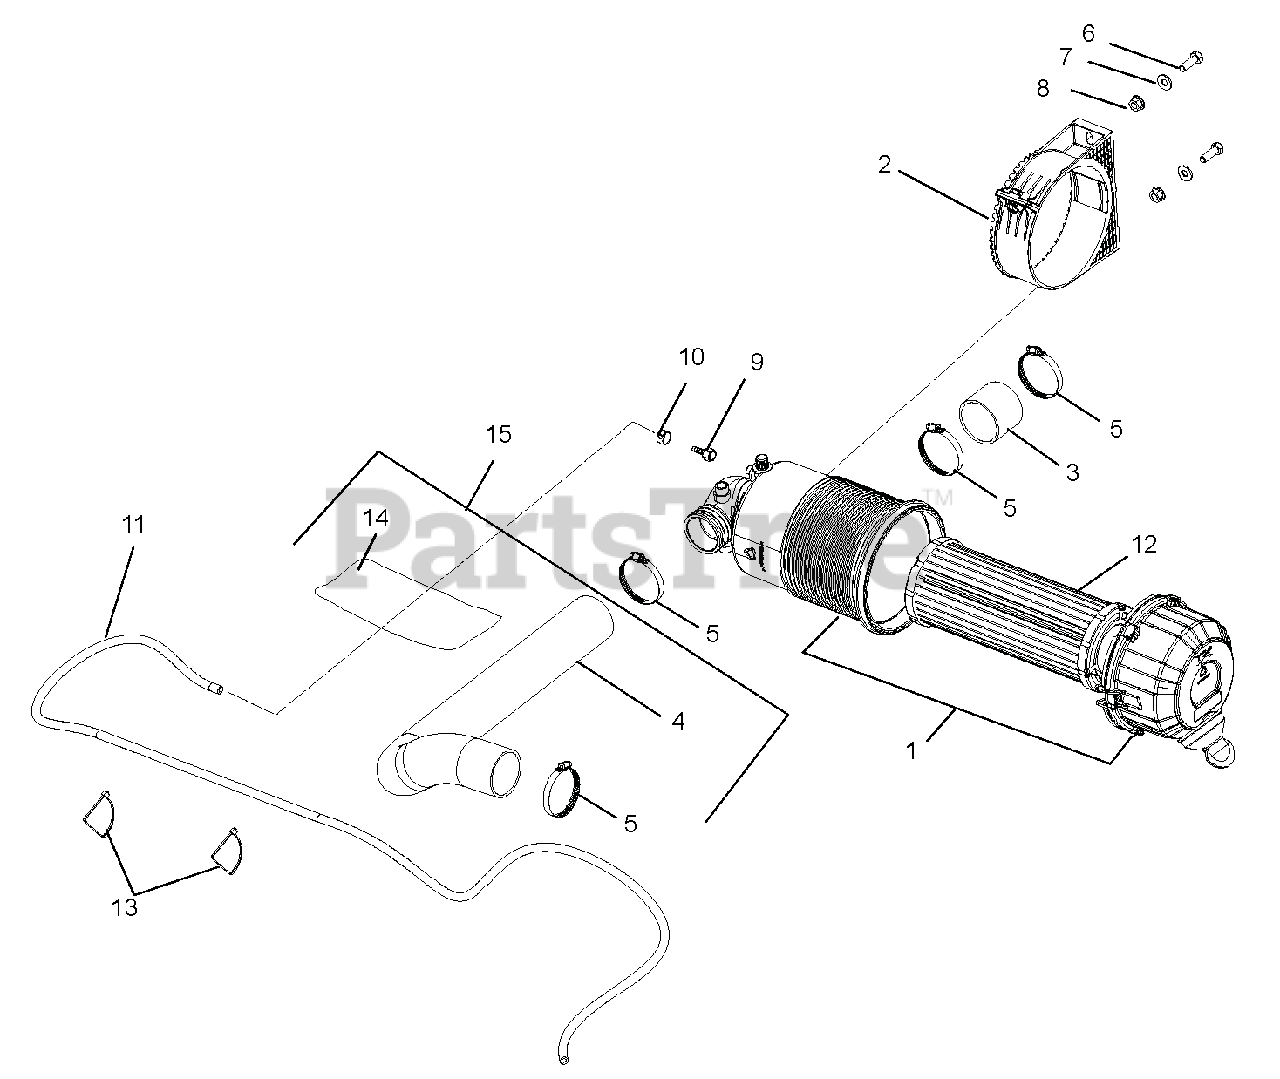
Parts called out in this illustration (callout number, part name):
1	ASM, AIR CLEANER 2012 EPA
2	CLAMP, AIR CLEANER BRACKET
3	INTAKE AIR FILTER COUPLER
4	INTAKE TUBE, ENGINE
5	CLAMP,HOSE,WRM DRV,1.81X2.75
6	@BLT-HEX .31-18X1.00 GR5 YWZC
7	WASHER FLAT 5/16 HARD ASTMF436
8	NUT HEX FLG TP LK 5/16-18ZNYCR
9	FITTING, 1/8-27 NPT, 3/16 BARB
10	CLAMP-HOSE, SPRING .188
11	HOSE, .188 LOW-PERM BULK GAS
12	FILTER AIR OUTER ELEMENT
13	CABLE TIE W/ TREE (.25 HOLE)
14	TAPE,ALUM 3M 425
15	ASM, INTAKE HOSE & HEAT TAPE
